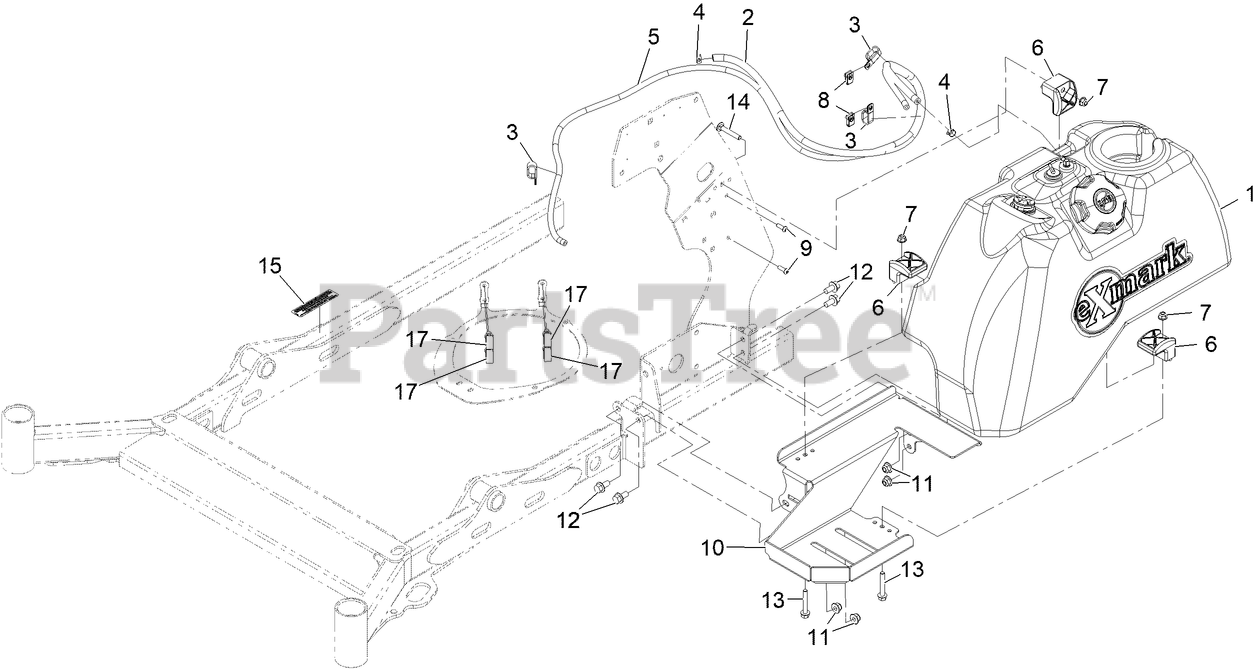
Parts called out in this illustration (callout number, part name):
1	ASM, FUEL TANK 8 GAL
2	HOSE-FUEL
3	CLAMP-R, DOUBLE TUBE
4	CLAMP-HOSE
5	HOSE-FUEL
7	NUT-HF, NI
9	SCREW-HSBH
10	Bracket, Fuel Tank
11	NUT-HF, NI
12	Screw-HH Flg 3/8-16 X 3/4
13	SCREW-HHF
14	BOLT-CARR
15	DECAL-ARRESTOR, SPARK
17	CLIP-TIE
